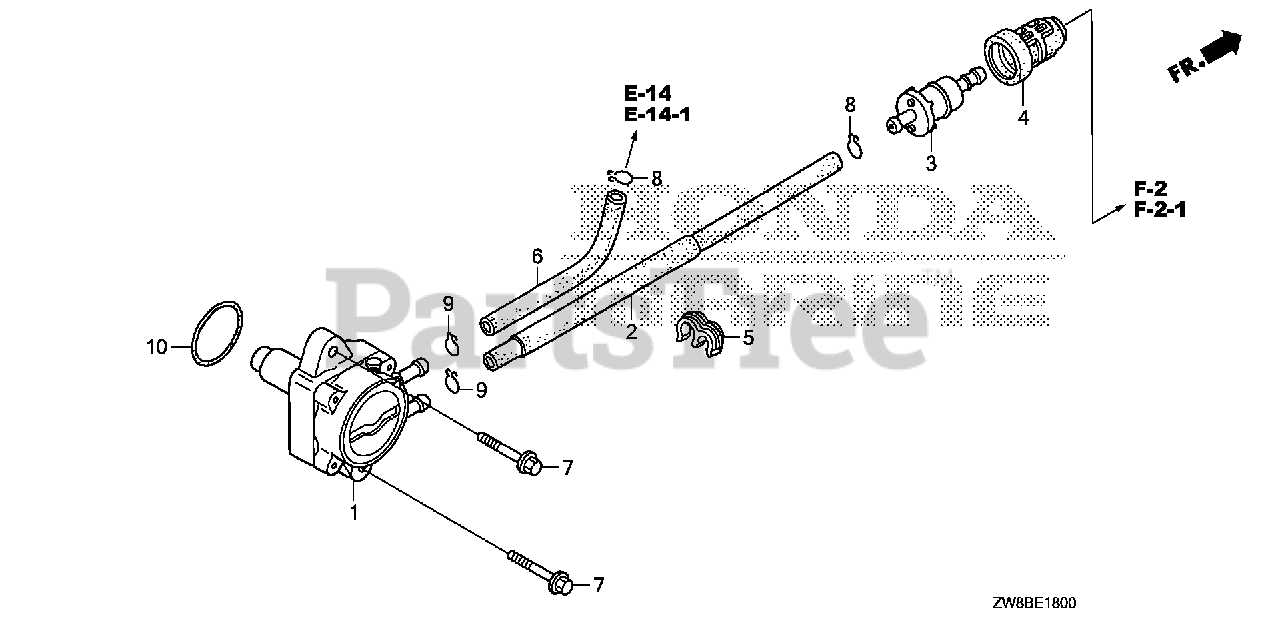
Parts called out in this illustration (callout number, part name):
1	PUMP ASSY., FUEL (MSDS)
2	TUBE B, FUEL
3	FILTER, FUEL
4	SUSPENSION, STRAINER
5	CLAMP, TUBE (7.5-11.5) (BLACK)
6	TUBE, FUEL
7	BOLT, FLANGE (6X22)
8	CLIP, TUBE (B10)
9	CLIP, TUBE (ENGINE NO.)
9	CLIP, TUBE (B12)
10	O-RING (31.2X2.4)
